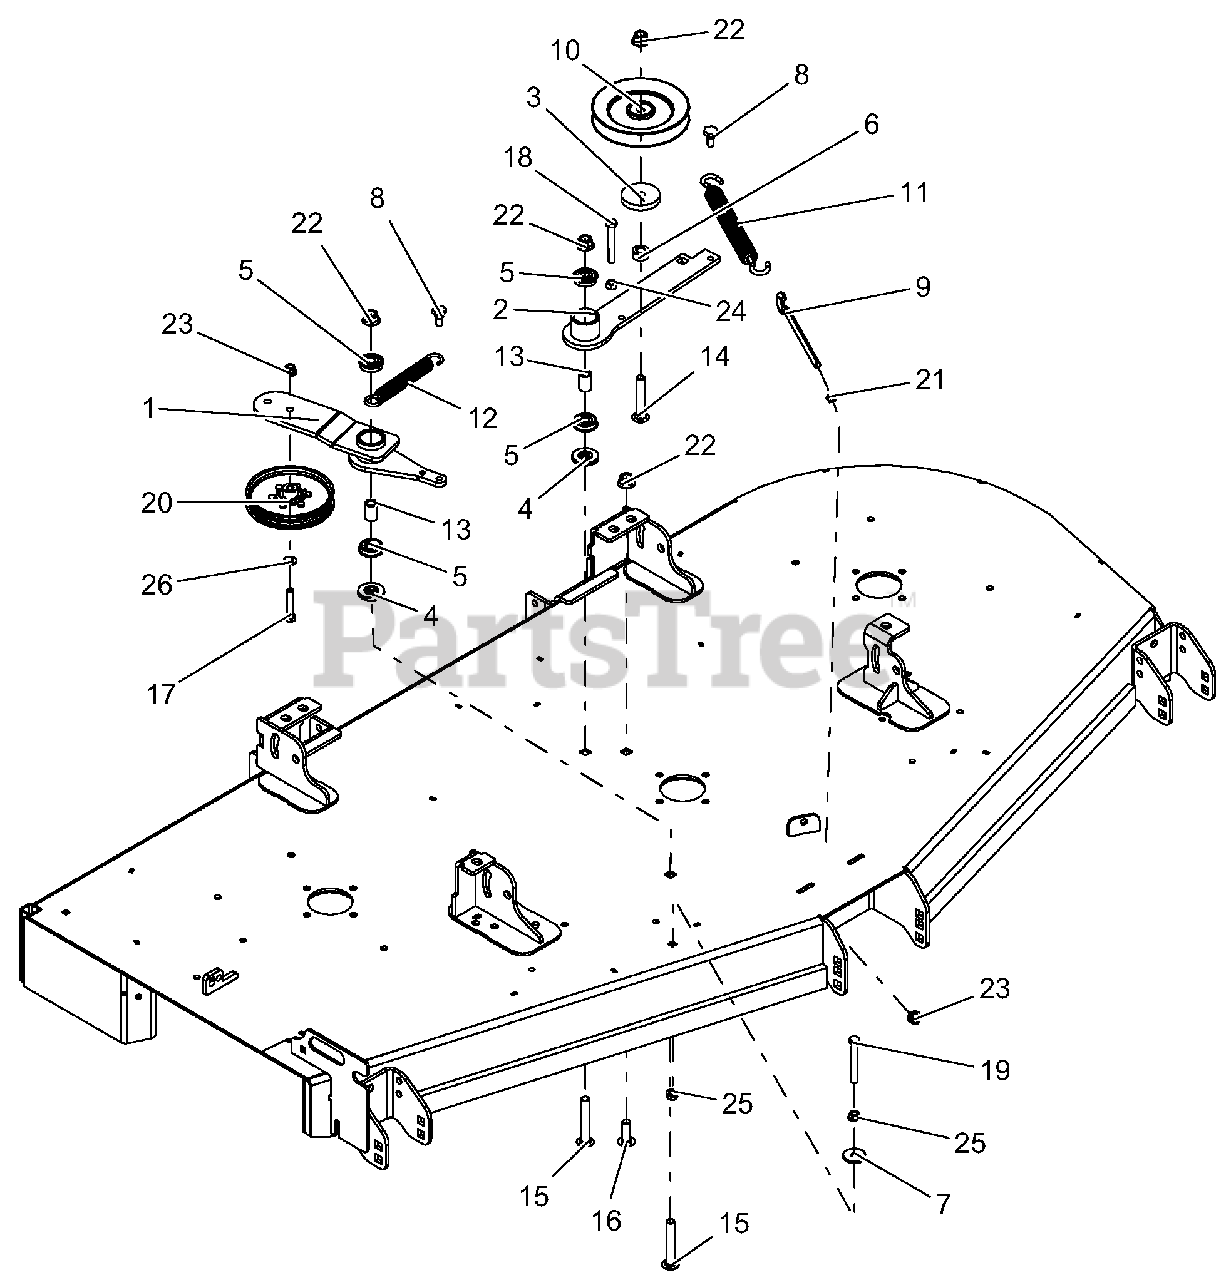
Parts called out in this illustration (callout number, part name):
1	WLDMT, DECK RH IDLER ARM
2	WLDMT, DECK PTO IDLER ARM-BLACK
3	CAP, IDLER BEARING SEALING
4	SPACER, IDLER ARM
5	BRG, BALL .501 X 1.38 X .438 SEALED
6	BSHG, SPCR .502 X .997.50 PM
7	WSHR-FL-STL .406X1.375X.135 YZ
8	BLT, SHLDR EP .38-16X.30 HEX YZ
9	BOLT, .38-16X6.00 .62 DIA EYE
10	SHEAVE, .50" ID X 6.00" OD V-IDLER
11	SPRG, EXTENSION
12	SPRG, EXTENSION
13	SPACER, .510 X .750 X 1.148
14	BLT-RDHDSQNK .50-13X3.00 G5Y
15	BLT-RDHDSQSHNK .50-13X3.25 YWZC
16	BLT-RDHDSQSHNK .50-13X1.50 YWZC
17	BLT-HEX .38-16X2.00 GR5 YWZC
18	BLT-HEX .38-16X2.75 GR5 YWZC
19	BLT-HEX .38-16X3.00 GR5 YWZC
20	PULLEY, FLAT IDLER .500 X .375 W/BRG
21	NUT, JAM .375-16 YWZC
22	NUT-LK-NYL-FLG .50-13 YWZC
23	NUT-LK-NYL-FLG .38-16 YWZC
24	NUT-HEX .38-16 YWZC
25	@NUT-SPNLK-FLG .375-16 YWZC
26	WSHR-FL-STL.406X.812X.065ZYW
